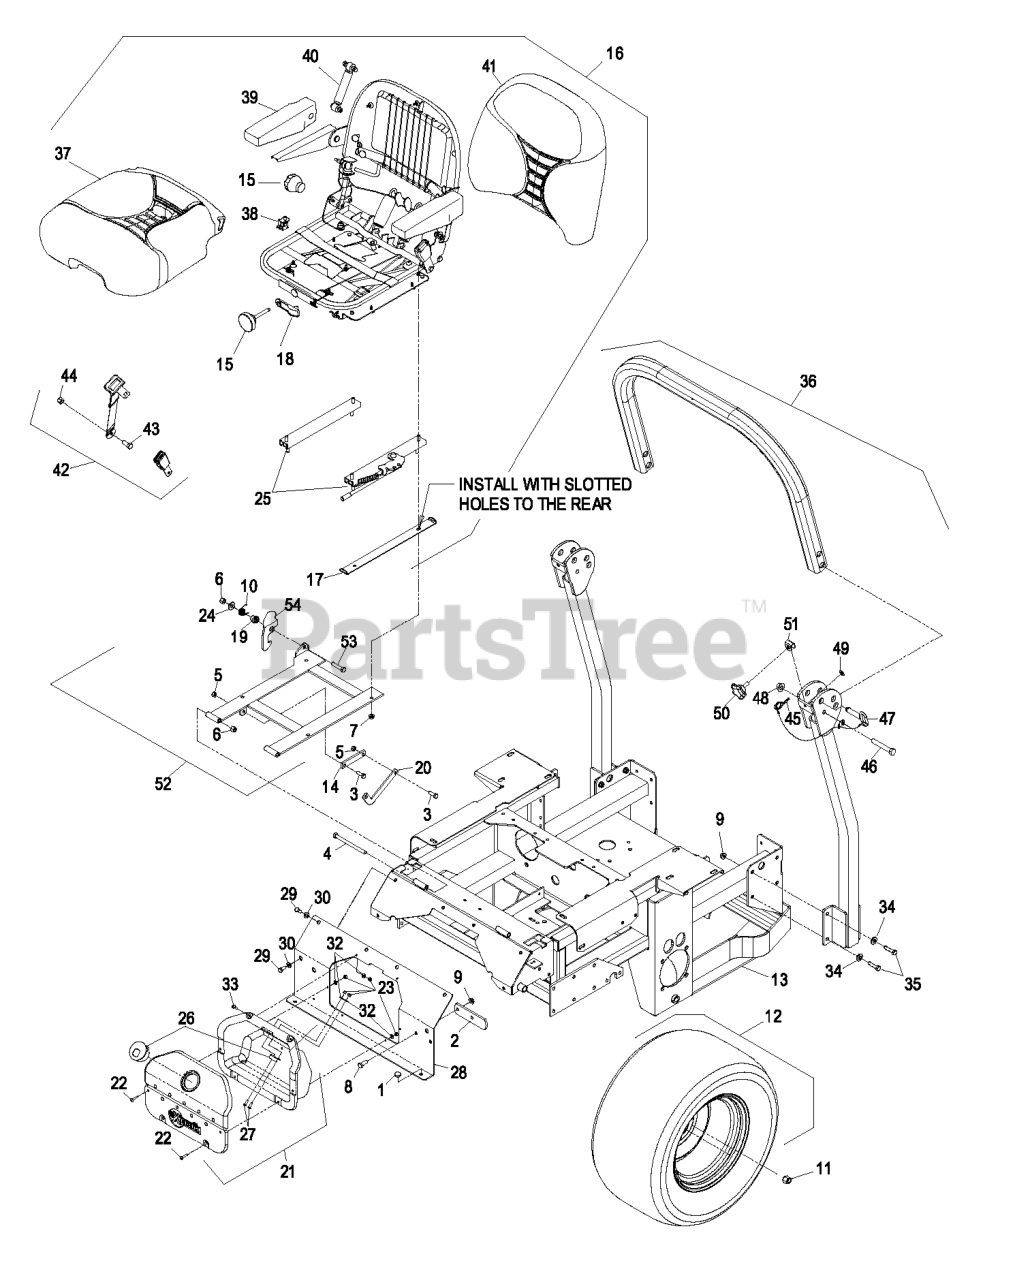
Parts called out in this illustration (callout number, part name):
2	STOP-BRAKE, PARK
3	SCREW-HH
4	SCREW-HH
5	NUT-LOCK, NI
6	NUT-LOCK, NI
8	SCREW-HH
9	NUT-HHF, WHIZ
10	SPRING-TORSION, LATCH
11	NUT-LUG
13	KIT,LZXS MAINFRAME W/DECA
14	LINK-STOP, SEAT
15	KNOB KIT
17	STOP-SEAT
18	WEIGHT INDICATOR KIT
19	BUSHING-LATCH, SEAT
20	LINK-SEAT STOP, LOWER
21	ASM,CUBBY
23	NUT-LOCK, NI
24	WASHER-FLAT
25	SEAT TRACK KIT
26	LATCH,CUBBY
27	SCREW-PPH
29	SCREW-HH
30	WASHER-PLAIN
32	WASHER-FLAT
33	SCREW-HEAD, TRUSS
34	WASHER-BELLEVILLE
35	SCREW-HH
37	BOTTOM CUSHION KIT
39	PAD-ARMREST
40	SHOCK ABSORBER KIT
41	BACK CUSHION KIT
42	SEATBELT KIT
43	SCREW-HH
44	NUT-LOCK, NI
45	HAIRPIN
46	SCREW-HH
47	PIN-FOLD, ROPS
49	NUT-PUSH
53	SCREW-HH
54	CATCH-LATCH, SINGLE
